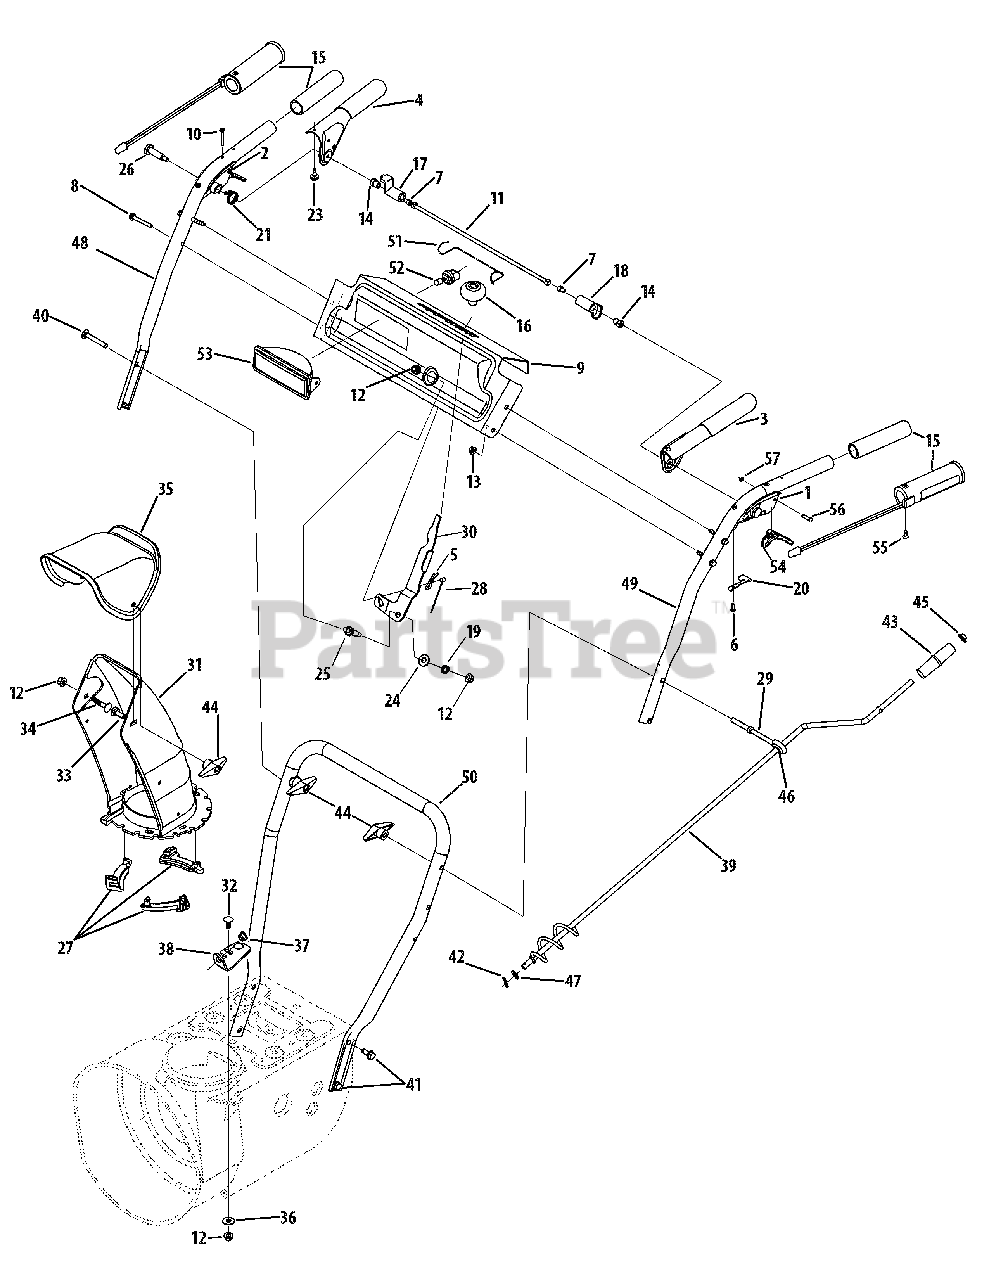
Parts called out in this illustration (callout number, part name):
1	Handle Assembly, Clutch Lock LH
2	Handle Assembly, Clutch Lock RH
3	Handle Assembly, Engage LH
4	Handle Assembly, Engage RH
5	Click Pin
6	Screw, #8-16 x .50
7	Screw, 1/4-20, 1.50
8	Hex Screw, 1/4-20, 1.50
10	Machine Screw, #10-24, 1.375
11	Pivot Rod
12	Flange Lock Nut, 5/16-18
13	Flange Lock Nut, 1/4-20
14	Shoulder Hex Nut, 1/4-20
15	Heated Grip
16	Shift Knob
17	Lock Plate
18	Clutch Lock Cam
19	Spring, .39 x .60 x .88
20	Clutch Lock Spring
21	Torsion Spring, 0.8156 ID x .3038
23	Rubber Bumper, .62 OD x .22
24	Flat Washer, .385 x .870 x .092
25	Shoulder Bolt, 5/16-18 x 0.905
26	Shoulder Screw, .43 x 1.3, 1/4-20
27	Chute Flange Keeper
28	Speed Selector Cable
29	Chute Crank Eye Bolt
31	Lower Chute, 5.0 Dia
32	Carriage Bolt, 5/16-18, 1.0
33	Carriage Bolt, 5/16-18, 1.0
34	Carriage Bolt, 5/16-18, .750
35	Upper Chute w/ Label
36	Washer, .349 x .879 x .063
37	Plastic Bushing, .380
40	Carriage Screw, 5/16-18, 2.25
41	Screw, 5/16-18, 0.75, Gr5
42	Cotter Pin, .072 x 1.13
43	Crank Knob, 1.0 Dia x 3.2
44	Wing Knob, 5/16-18
45	Push Cap, 3/8 Rod
46	Grommet, .44ID x .94 OD x .50
47	Flat Washer, .375 x .738 x .063
51	Lens Retainer
52	Halogen Lamp,12V, 27W
53	Lamp Lens Assembly
54	Steering Triggers
55	AB Screw
57	E-Ring
